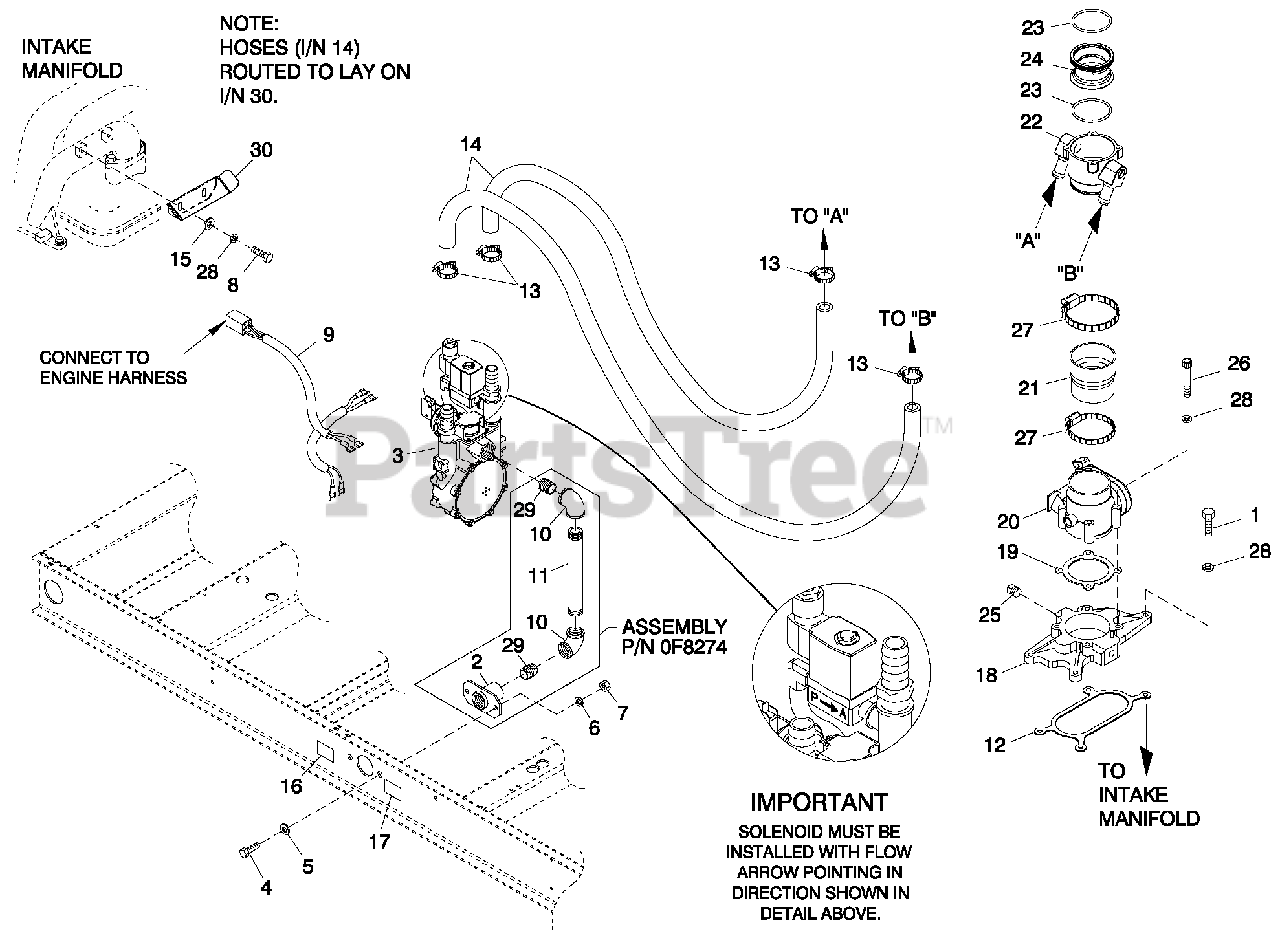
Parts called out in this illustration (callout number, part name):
1	SCREW HHC M6-1.0 X 35 G8.8 BLK
2	FLANGE FUEL INLET
3	REG ASSY 6.8L 70KW LPV CPL
4	SCREW HHC M8-1.25X 20 G8.8
5	WASHER FLAT 5/16-M8 ZINC
6	WASHER LOCK M8-5/16
7	NUT HEX M8-1.25 G8 CLEAR ZINC
8	SCREW HHC M6-1.0X 20 G8.8
9	HARNESS,FUEL JUMPER SINGLE REG
10	ELBOW 90D 3/4NPT
11	NIPPLE PIPE 3/4NPT X 7
12	GASKET ADAPTER THROT BODY
13	CLAMP HOSE #10 .56-1.06
14	HOSE 3/4 ID SAE-30R2 (38.5" LG)
15	WASHER FLAT M6
16	DECAL INLET PRESSURE
17	DECAL FUEL INLET NG (NATURAL GAS APPLICATION)
18	ASSY,ADAPTER,THROTTLE BODY
19	GASKET, GOVERNOR ACTUATOR
20	ACTUATOR BOSCH 60, GOVERNOR
21	REDUCER 3.0" TO 2.75" TURBO
22	MIXER, 40/60MM ACTUATOR ASSY
23	O-RING 2-3/4X3/32X2-15/16
24	VENTURI, THROTTLE 36MM
25	PLUG STD PIPE 1/4 STEEL SQ HD
26	SCREW SHC M6-1.0 X 50 C8.8
27	CLAMP HOSE #44 2.31-3.25
28	WASHER LOCK M6-1/4
29	NIPPLE CLOSE 3/4X 1.375
30	BRACKET, HOSE RISER
